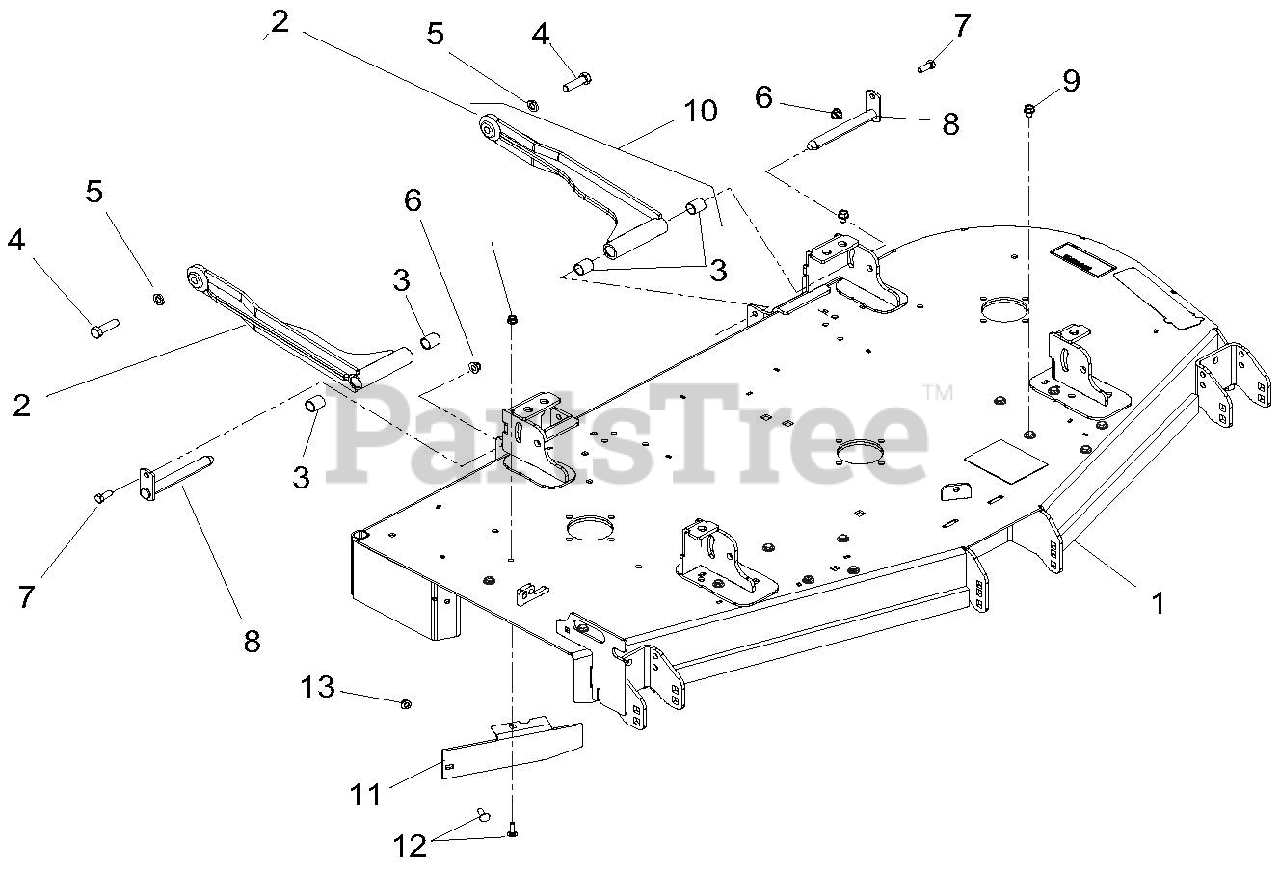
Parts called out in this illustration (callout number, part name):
1	WMT, 60in SIDE DISCH DECK
1	WMT, 66in SIDE DISCH DECK
1	WMT, 72in SIDE DISCH DECK
1	WMT, 52in SIDE DISCH DECK
2	WMT, DECK STABILIZER ARM
3	BRG, .75 X .875 X 1.00
4	BLT-HEX .50-13X1.75 GR5 YWZC
5	WSHR-LK .50X.125 REG YWZC
6	NUT-LK-NYL-FLG .38-16 YWZC
7	BLT-HEX .38-16X1.00 GR5 YWZC
8	WLDMT, MOWER MTG. PIN
9	SCR-TAP .38-16X.50 HWH
10	PUSH ARM ASSEMBLY
11	52" BAFFLE
11	60" BAFFLE
11	66" BAFFLE
11	72" BAFFLE
12	BLT-RDHDSQNK .31-18X1.00 G5YZ
13	NUT-LK-NYL-FLG .31-18 YWZC
